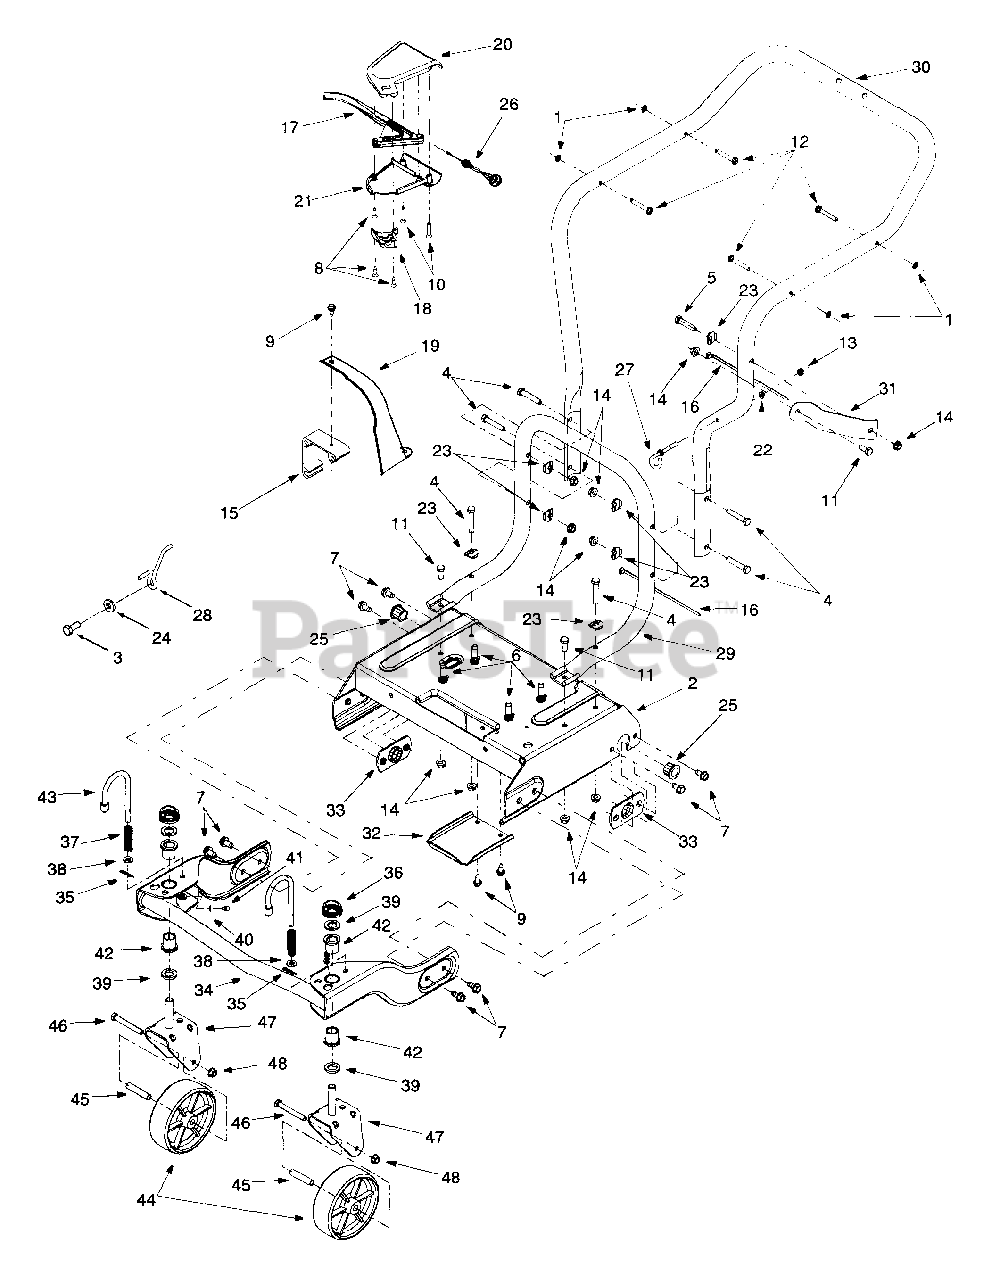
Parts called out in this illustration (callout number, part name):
1	Nut, Push, .25
3	Screw, Hex Cap, 5/16-24 x .75
4	Screw, Hex Cap, 5/16-18 x 1.75
5	Screw, Hex Cap, 5/16-18 x 1.5
6	Screw, Hex Wash Hd Tapp, 3/8-16 x 1.25
7	Screw, Hex Wash Hd Tapp, 5/16-18 x .62
8	Screw, Phil Cntrsnk, #10-12 x .75
9	Screw, Hex Wash Hd, 1/4-14 x .62
10	Screw, Phil Cntrsnk, #10-16 x 1.25
11	Screw, Hex Cap, 5/15-18 x .75 GR5
12	Pin, Stud, .250 x 1.75
13	Nut, Hex, 1/4-28
14	Nut, Hex Flange Lock, 5/16-18 GR5
15	Adapter, Engine Mtg
16	Cable Tie
17	Lever, Drive Control
18	Cap, Cable Mtg
19	Belt Cover
20	Upper Clutch Cover
21	Lower Clutch Cover
22	Washer, Lock, 1/4
23	Saddle Washer, .320 x .93
24	Washer, Flat, .344 x .75 x .12
25	Bearing, Flange, .631 ID x .72 OD
26	Cable, Clutch, 56.0
27	Eye Bolt
28	Belt Keeper
35	Pin, Internal Cotter
36	Cap, Push, 5/8
37	Spring, Compression
38	Washer, Flat, .330 x .630 x .06
39	Washer, Flat, .64 x 1.12 x .12
40	Washer, Flat, .203 IDx.403 OD .040
41	Fitting, Lube, 3/16
42	Bearing, Flange, .632 ID
43	Pin, Front Wheel Lock
44	Wheel, 6.00 x 2.00
45	Spacer, .384 ID x .5 OD x 2.3 Lg
46	Screw, Hex Cap, 3/8-16 x 3.0
48	Nut, Hex Flange Lock, 3/8-16
